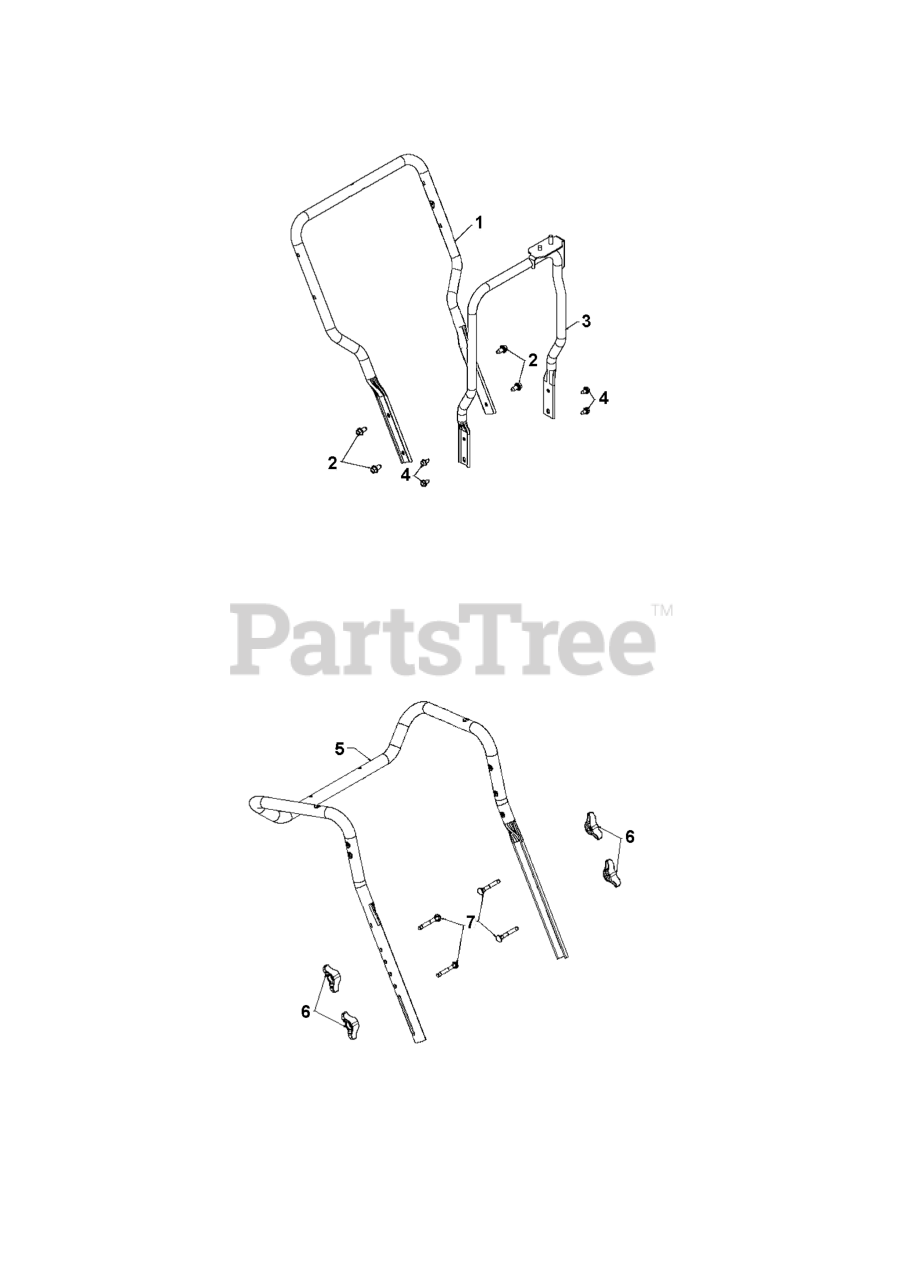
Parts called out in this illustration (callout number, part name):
1	HANDLE.LOWER.498
2	SCREW, 3/8-16X3/4
3	SUPPORT WELDMENT, CHUTE PAINTE
4	BOLT.5/16HEX.WHS.HD
5	HANDLE.UPPER.498
6	KNOB, DEFLECTOR
7	BOLT.CARRIAGE.5/16-18 X 2.25
